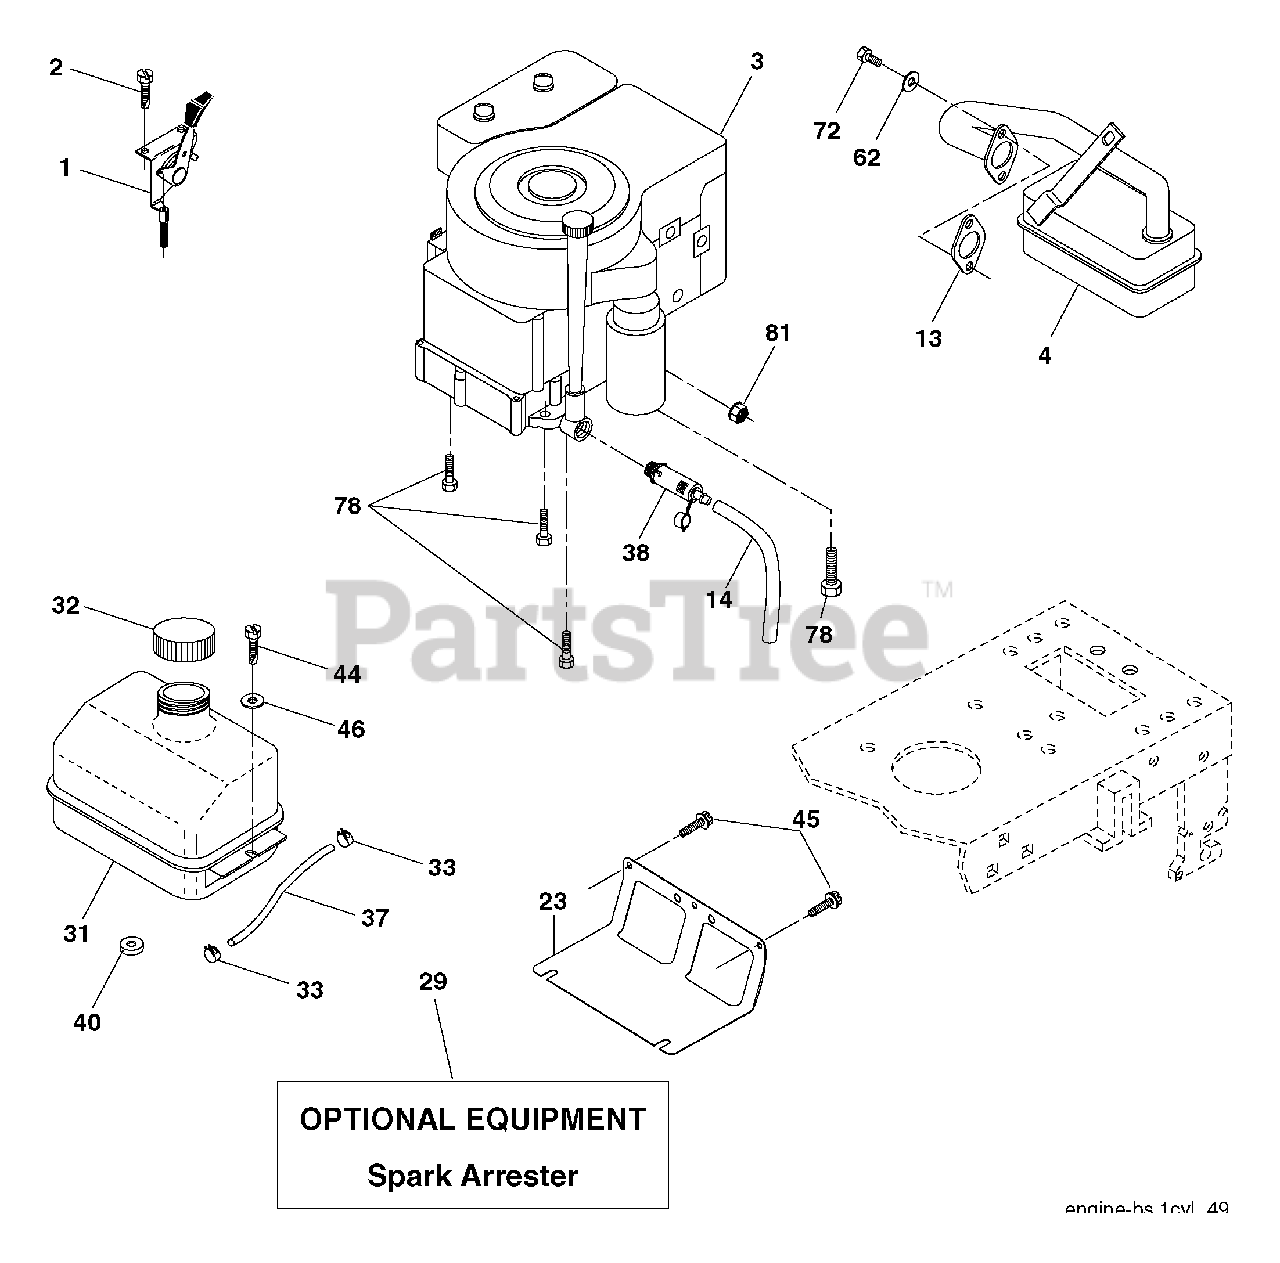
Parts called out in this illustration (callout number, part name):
1	Control, Throttle
2	Screw Hex Thd Cut 1/4-20 x 1/2
4	Muffler
13	Muffler Gasket
14	Tube Oil Drain
23	Shield, Browning/Debris Guard
29	Arrester, Spark
32	Cap, Fuel
33	Clamp, Hose Blk
37	Line, Fuel
38	Plug Drain Oil Easy
40	Bushing Snap
44	Screw Hex Wsh Thdrol 1/4-20 x 3/4
45	Screw Hex Wsh Thdrol 3/8-16 x 3/4
46	Washer 9/32 x 7/8 x 16 Ga.
62	Washer Split
72	Screw 5/16-18 x 3/4
78	Screw 3/8-16 x 1-1/4
81	Nut Keps Hex 1/4-20 unc
